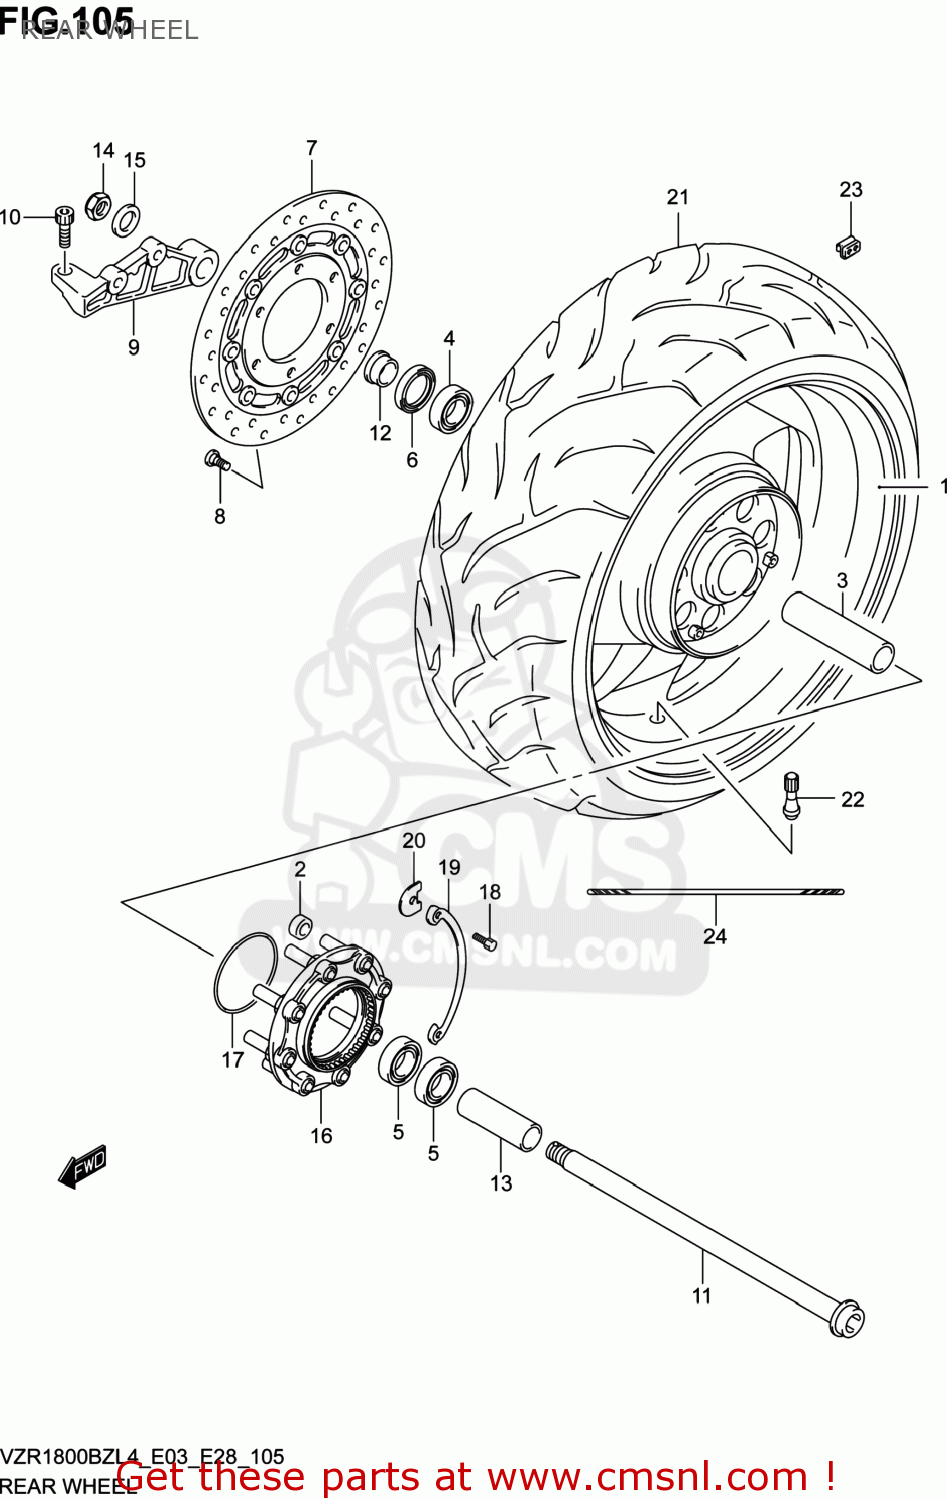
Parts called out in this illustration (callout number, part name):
1	WHEEL,RR(18M/CXMT8.50)
2	BUSH
3	SPACER,RR WHEEL BEARING
4	BEARING(25X52X15)
5	BEARING
6	SEAL,OIL(32X52X7)
7	DISC,RR BRAKE
8	BOLT(8X21)
9	BRACKET,RR CALIPER
10	BOLT(12X40)
11	AXLE,RR
12	SPACER,RR AXLE,R
13	SPACER,RR AXLE,L
14	NUT
15	WASHER(22X35X2)
16	JOINT ASSY,RR HUB DRIVEN
17	O RING(D:2.4,ID:79.8)
18	BOLT(6X16)
19	WASHER,RR HUB DRIVEN JOINT
20	WASHER,THRUST
21	TIRE,RR
22	VALVE ASSY,WHEEL RIM(TR412)
23	BALANCER,WHEEL(10G)
24	TAPE,WHEEL
